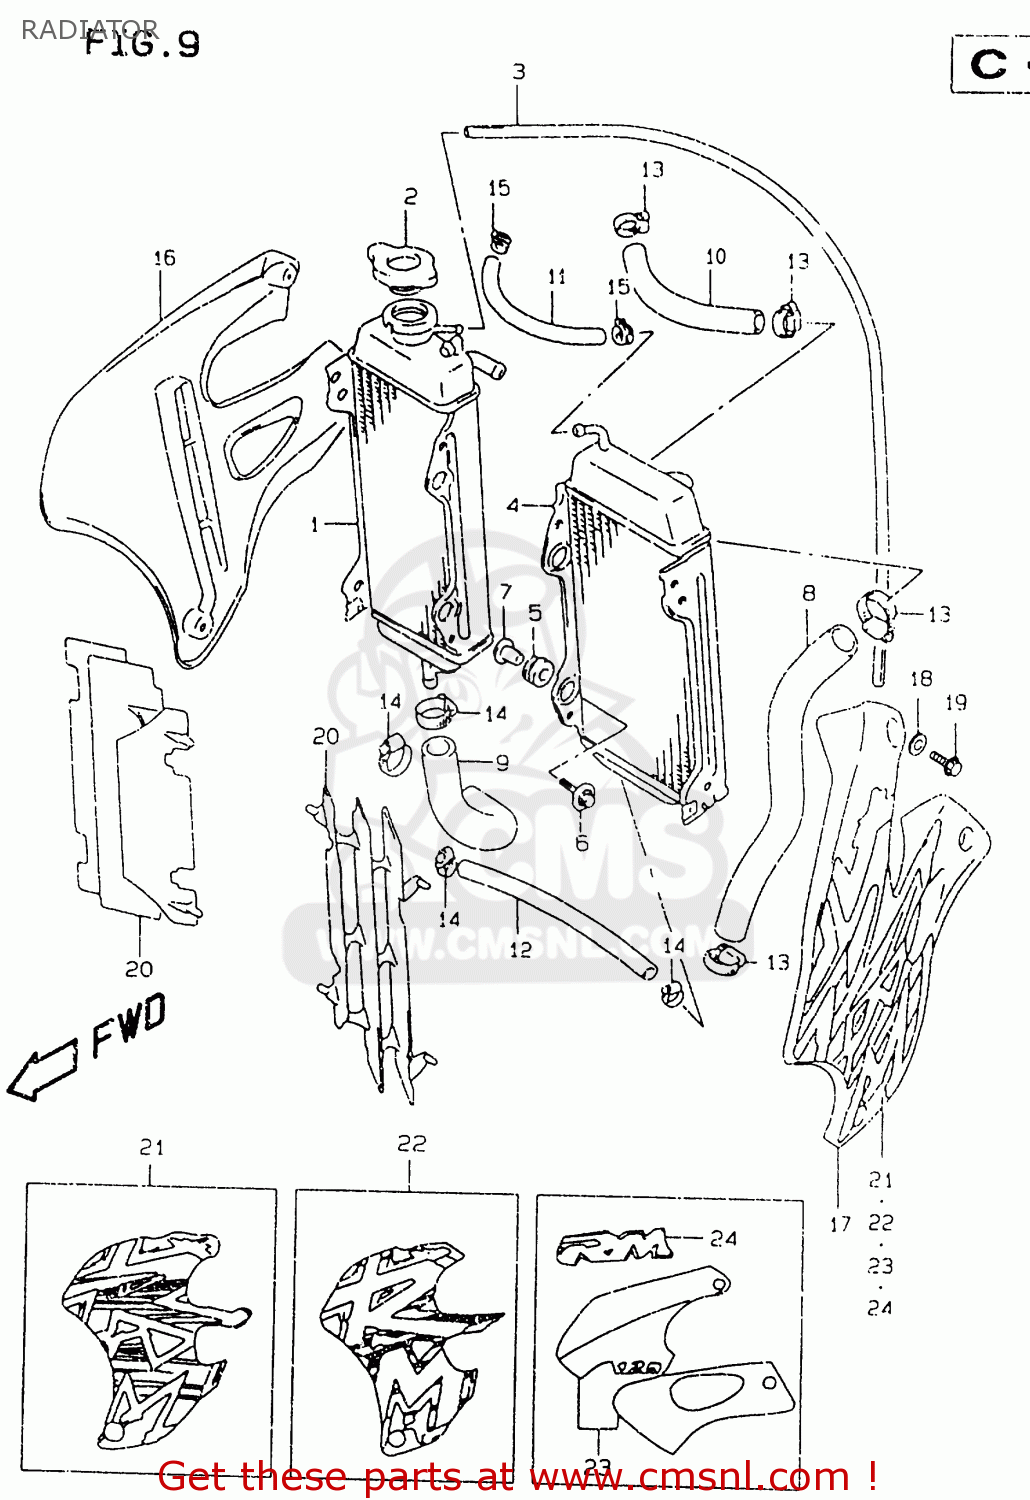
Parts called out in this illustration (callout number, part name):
1	RADIATOR,WATER,R
2	CAP,RADIATOR
3	HOSE (5X8X2000)
4	RADIATOR,WATER,L
5	CUSHION,RADIATOR LWR
6	BOLT(6X25)
7	SPACER(6.5X10.5X14.1)
8	HOSE,RADIATOR INLET
9	HOSE,RADIATOR OUTLET
10	HOSE,RADIATOR JOINT NO.1
11	HOSE,RADIATOR BYPASS
12	HOSE,RADIATOR JOINT
13	CLAMP
14	CLAMP
15	CLIP
16	COVER,RADIATOR,R
17	COVER,RADIATOR,L
18	WASHER
19	BOLT
20	LOUVER,RADIATOR
21	EMBLEM,RADIATOR COVER
22	EMBLEM,RADIATOR COVER,R
23	TAPE SET,RADIATOR COVER
24	EMBLEM,RADIATOR COVER,R
